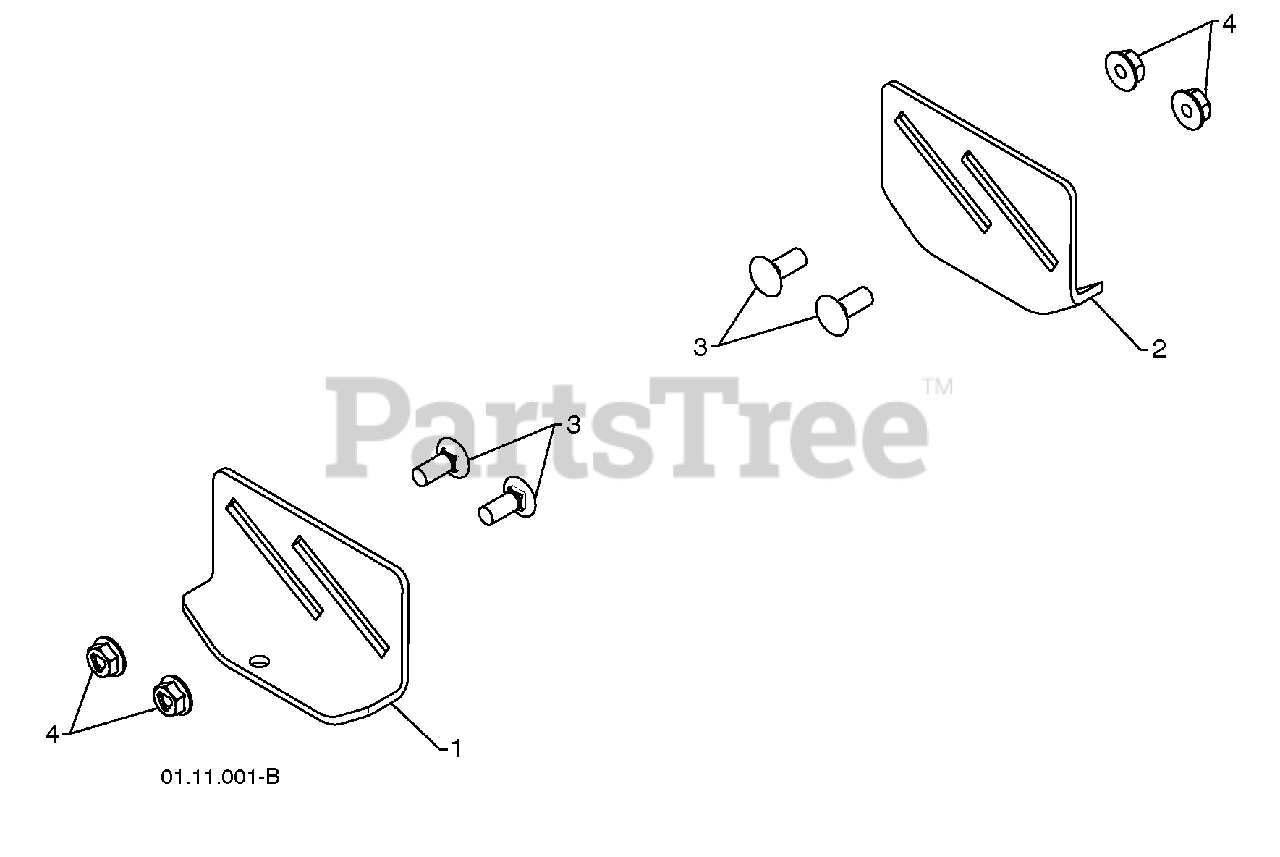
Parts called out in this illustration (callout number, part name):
1	SKID PLATE LH
2	SKID PLATE RH
3	CARRIAGE BOLT 5/16-18 X .75
4	NUT 5/16-18
